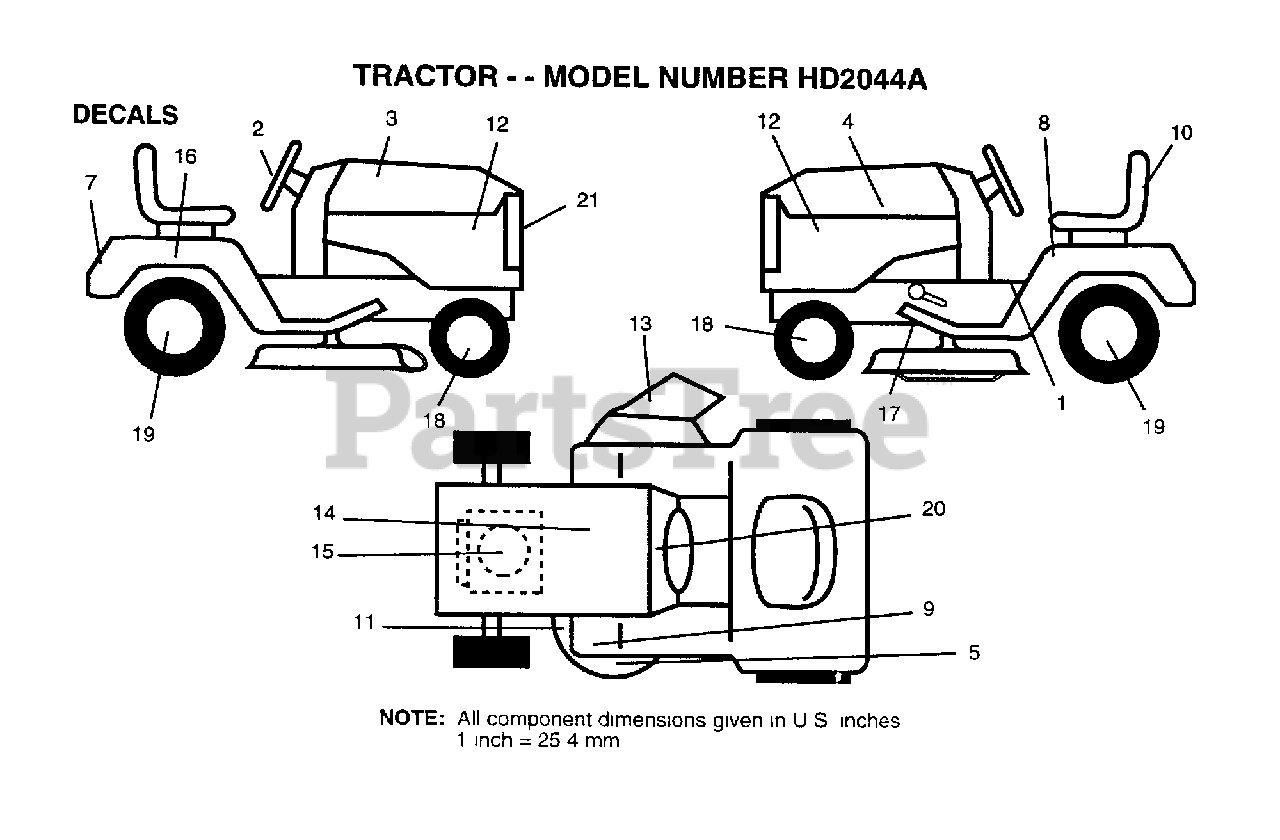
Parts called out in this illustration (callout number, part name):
1	DECAL BRAK PARK
2	DECAL.INST.WHL.ST
3	DECAL.HD.RH.20HP.
4	DECAL.HD.LH.20HP.
5	DECAL.DECK.MULCH.
7	DECAL.FENDER.HDEP
8	DECAL CAUT FEND
9	DECAL CLUT/BRAKE
10	DECAL.SEAT.WEED.
11	DECAL.HD2044A
12	DECAL.PNL.SD.HDEP
13	"DECAL, WARNING"
14	DECAL.BATRY.3-3908
15	DECAL.PARTS.ONAN.
17	DECAL.HD2044A
18	"DECAL.HUBCAP.8"""
19	DECAL.HD2044A
20	DECAL INST OP DAS
21	DECAL.GRILLE.HDPT
